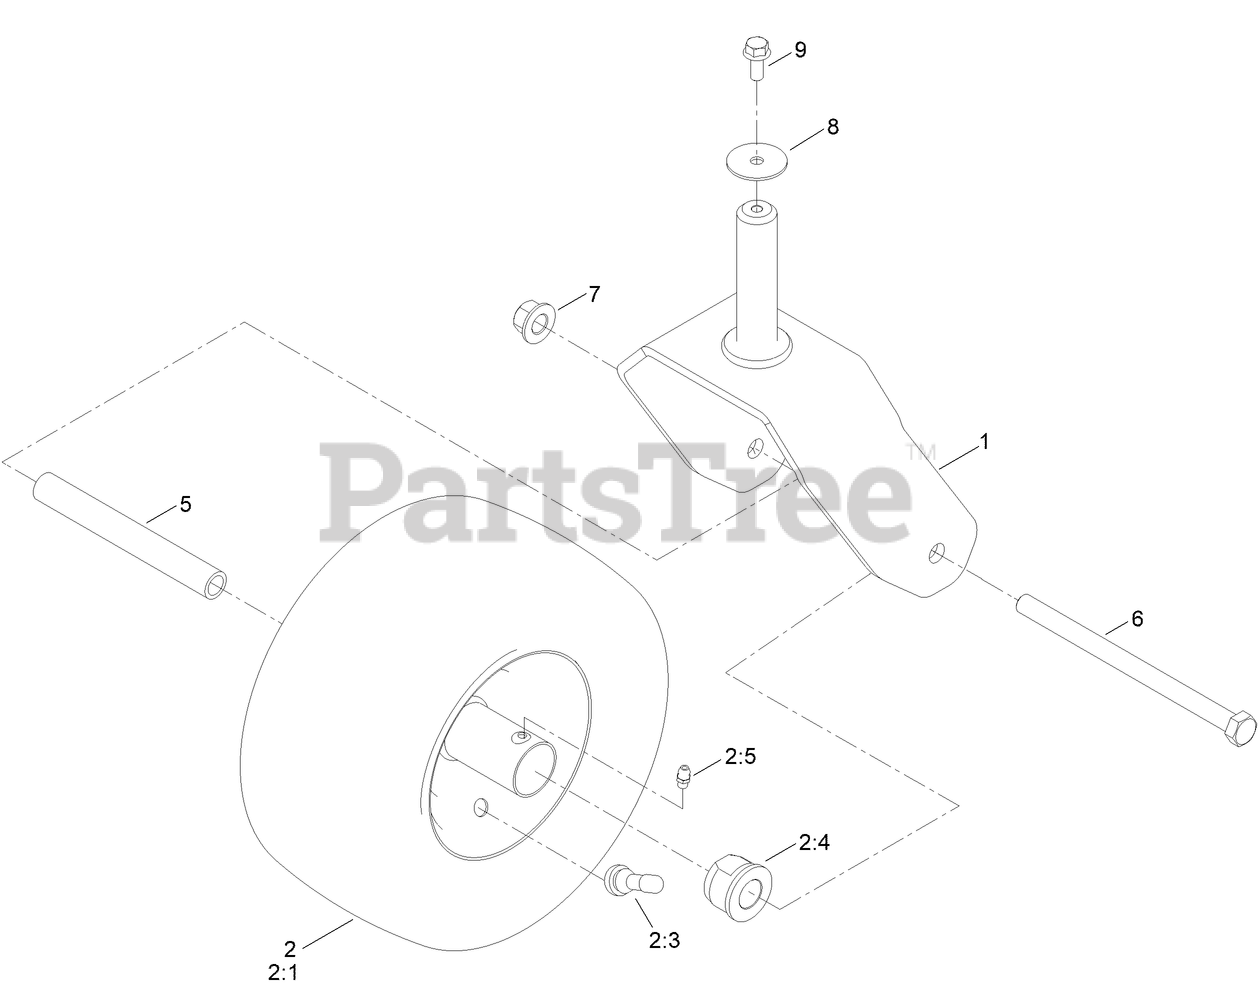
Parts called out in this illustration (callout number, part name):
1	FORK ASM
2	TIRE ASM
2:4	BUSHING-FLANGE
2:5	FITTING-GREASE
5	SPACER-SPANNER
6	SCREW-HH
7	NUT-HF
8	WASHER-FLAT
9	SCREW-HHF
